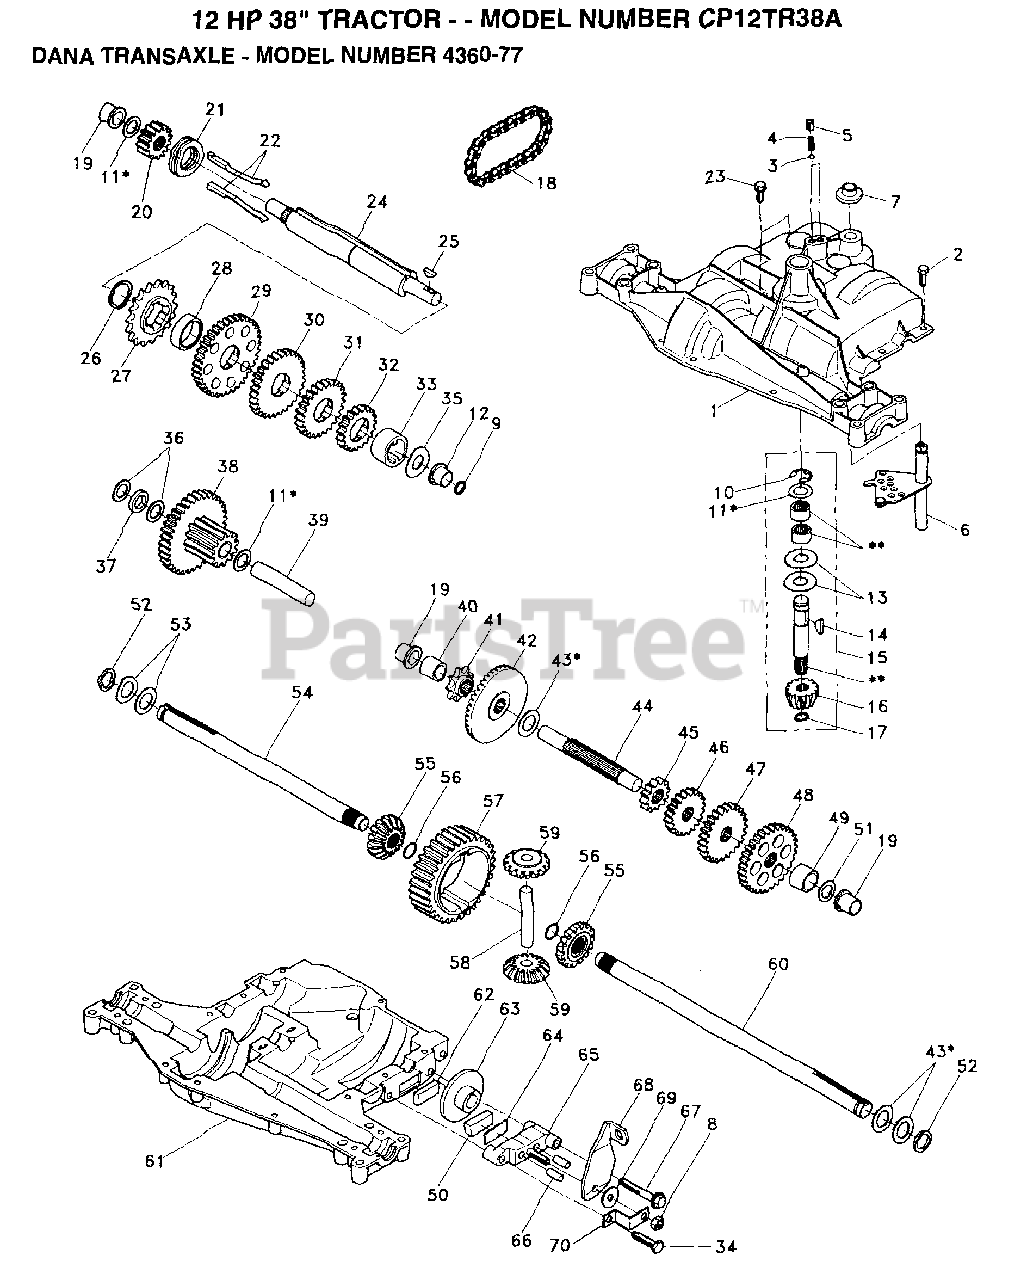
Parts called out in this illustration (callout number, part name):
1	HOUSING UPPER TRN
4	"SPRING, DETENT LT"
5	"SCREW, SET LT"
6	KIT SHIFTER ASM
7	SHIFTER BOOT
8	NUT.LOCK.5/16-24
9	SEAL OIL DANA5416
11	ASM KIT SHIM 4689
13	WASHER T
14	KEY WOODRUFF-DANA
15	AS KIT INPUT SHFT
16	PINION 14T T
17	"RING,RETAINING LT"
18	"CHAIN,24 PTCH LT"
19	BEARING.FLNG.5510
20	GEAR SPUR 14 TTH
21	COLLAR CLUTCH
22	ASM KIT CLTCH KEY
23	SCREW TAP W/SEAL
24	SHAFT INTERM DANA
25	WOODRUFF KEY
26	"RING,RETAINING LT"
27	SPROCKET 18T T
28	SPACER YT
29	GEAR SPUR 37 TTH
31	GEAR 25T LT
32	SPUR GEAR 19T
33	SPACER
34	"SCREW, TAPPING LT"
35	"WASHER, PLAIN LT"
36	WASHER 025
37	SPACER
38	ASSM GEAR COMB
39	SHAFT IDLER
40	SPACER T
41	SPROCKET 9T LT
43	ASM KIT SHIM
44	SHAFT T
45	GEAR SPUR 12 TTH
47	"GEAR, SPUR 25T LT"
48	"GEAR, SPUR 31T LT"
50	PUCK T
51	WASHER 060
52	NEOPRENE WASHER
53	WASHER 031
55	GEAR 15T T
56	"RING,RETAINING LT"
58	SHAFT T
59	GEAR 1ST T
61	HOUSING LOWER TNS
62	PUCK T
63	BRAKE DISC. T
64	SPACER LT
66	PIN T
69	WASHER LT
